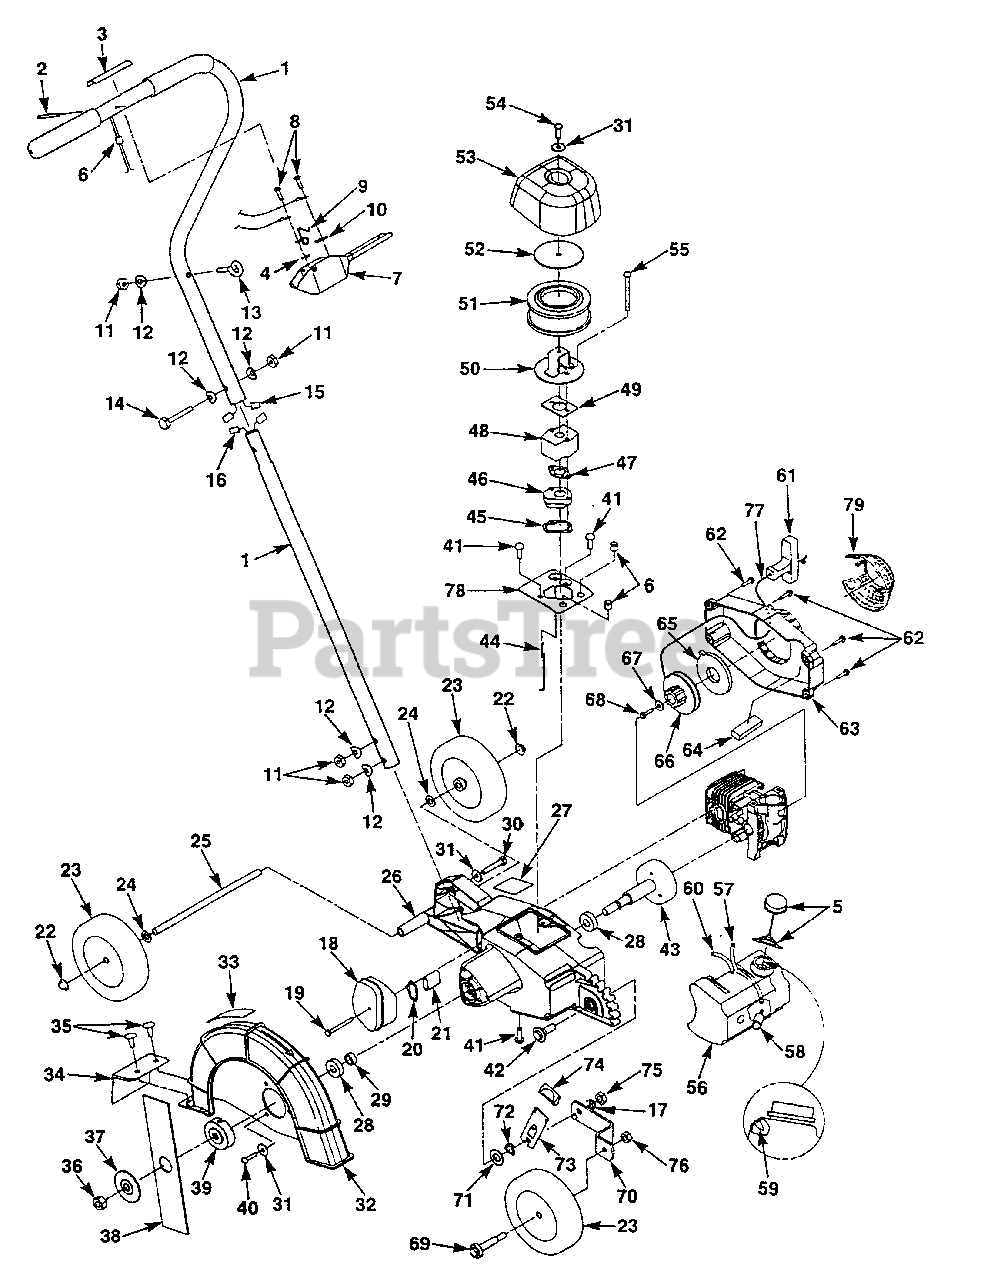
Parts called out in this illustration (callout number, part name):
1	HANDLE ASSEMBLY
2	PIN-Roll
3	DECAL-Operation
4	WASHER-Flat
5	CAP & RETAINER
6	BUSHING-Flange
7	BAIL-O.P.C.
8	SCREW-Thread Form (8-16 x 5/8")
9	SWITCH-O.P.C.
10	BRACKET-Retaining
11	NUT-Hex C/Lock (1/4-20)
12	WASHER-Curved
13	EYEBOLT
14	SCREW-Cap Hex Hd.(1/4-20 x 1 1/4")
15	HARNESS-Wire
16	HARNESS-Wire
17	WASHER-Lock
18	MUFFLER
19	SCREW-Sems Hex Hd.
20	GASKET-Muffler
21	SCREEN-Muffler
22	NUT-Push 3/8"
23	TIRE-(5")
24	WASHER-Flat
25	AXLE-Rear
26	ENGINE-HOUSING ASSY
27	DECAL-Warning
28	BEARING-Ball
30	SCREW-Cap Hex Hd.(1/4-20 x 2")
31	WASHER-Flat (1/4)
32	BLADE GUARD ASSEMBLY
33	DECAL-Warning
34	FLAT-Drag
35	RATCHET FASTENER
36	NUT-Hex (L.H.) (7/16-20)
37	WASHER-Cupped
38	BLADE-(2" x 9")
39	WASHER-FLANGED
40	SCREW-Thread Form.(10-24 x 7/8)
41	SCREW-Thd. Form (10-24 x 3/4)
42	BOLT-Shoulder
43	DRUM-Clutch
44	LINK-Air Vane
45	GASKET-Heat Dam
46	HEAT DAM & REED
47	GASKET-Carburetor
48	CARBURETOR-Walbro
49	GASKET-Carburetor
50	PLATE-Filter
51	AIR FILTER
52	WASHER-Filter
53	COVER-Air Filter
54	SCREW-Truss Hd. (10-24 x 3/4")
55	SCREW-Hex Sems (10-24 x 2")
56	FUEL TANK ASSEMBLY
57	TUBING-Rubber
58	FILTER-Fuel
59	VALVE-Duck Bill
60	TUBING-Rubber
61	GRIP-Starter
62	SCREW-Thd. Form (#8 x 3/4")
63	HOUSING-Starter
65	SPRING & CONTAINER
66	PULLEY-Starter
67	WASHER-Retaining
68	SCREW-Thd. Form (10-24 x .75)
69	BOLT-Shoulder
70	ARM-Wheel Support
71	WASHER-Flat
72	WASHER-Belleville
73	SPRING-Index
74	KNOB-Index Spring
75	NUT-Hex Lock
76	NUT-Hex W/Washer
77	ROPE-Starter
78	COVER-Engine Housing
79	SCREEN-Starter Housing
